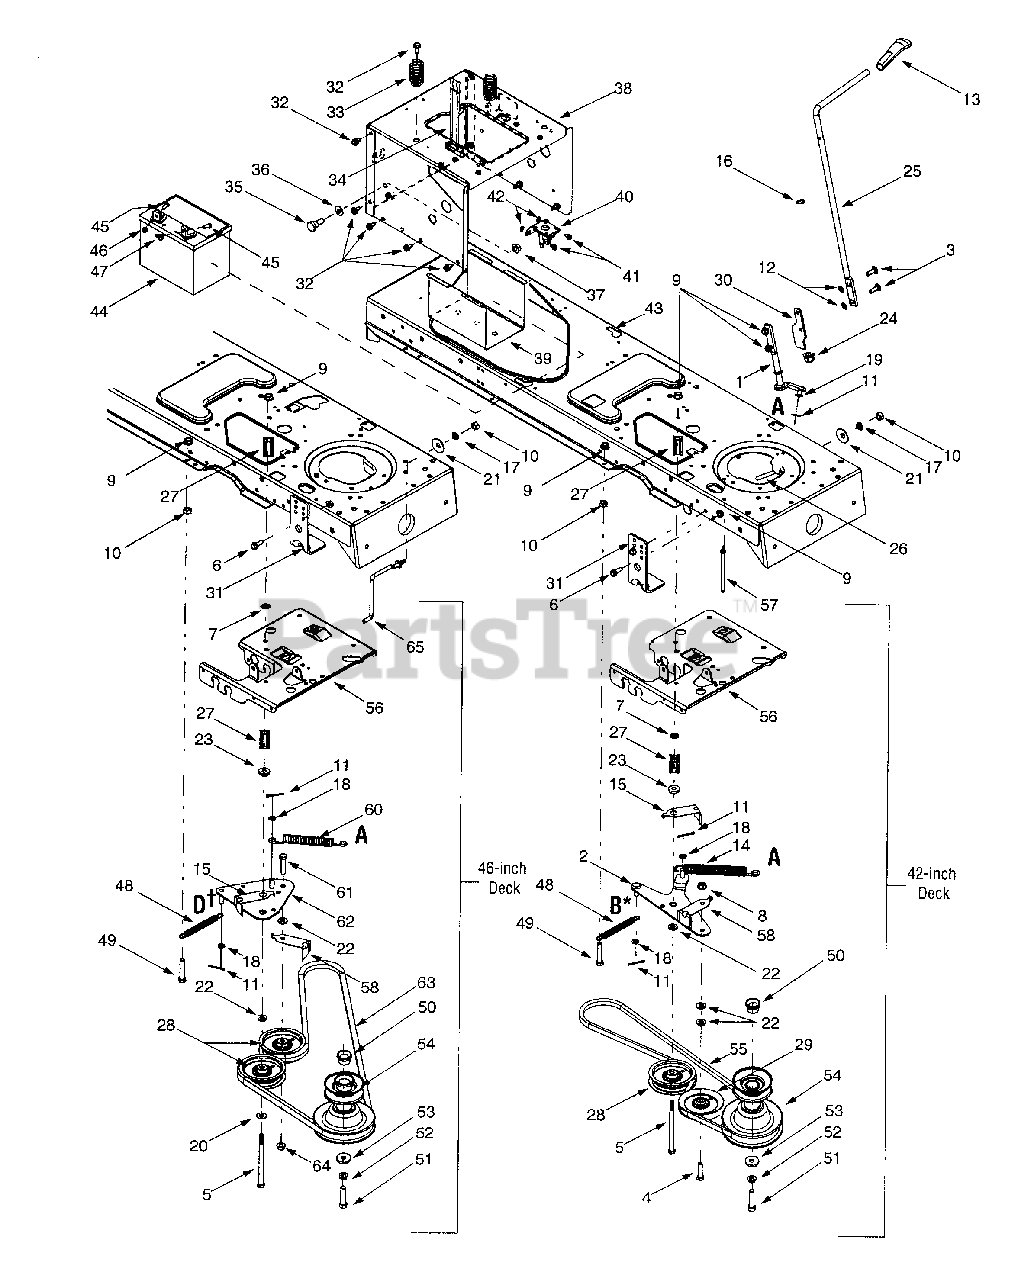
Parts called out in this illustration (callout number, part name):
1	PTO Engage Lever Assembly
4	Hex Cap Screw, 3/8-16 x 1.5
5	Hex Cap Screw, 3/8-16 x 5.5
6	Hex Head Washer Screw, 5/16-18 x .875
7	Push Nut, 3/8
8	Flange Lock Nut, 3/8-16
9	Flange Lock Nut, 5/16-18
10	Hex Nut, 5/16-18
11	Cotter Pin, 1/8 x 1.25
12	Speed Nut, .3125
13	PTO Knob
14	Extension Spring, .75 x 6.75
15	Belt Guard
16	Flat Washer, .510 x .750 x .033
17	Lock Washer, 5/16
18	Flat Washer, .385 x .62 x .063
19	Flat Washer, 5/16
20	Flat Washer, .406 x .875 x .059
21	Bell Washer, .39 x 1.13 x .062
22	Flat Washer, .407 x .812 x .135
23	Shoulder Spacer, .380
24	Hex Split Flange Bearing, .5
26	Belt Keeper Rod
27	Spacer, 3/8 x 1.54
28	Idler Pulley, 3.5
29	Idler Pulley, 4.0
32	Self Tapping Screw, 5/16-18 x .625
33	Compression Spring, 1.28 x 3.5
34	Battery Strap
35	Shoulder Screw, .625 x .5, 7/16-20
36	Bell Washer, .45 x 1.0 x .062
37	Flange Lock Nut, 7/16-20
41	Self Tapping Screw, 1/4-20 x.5
42	Lock Washer, 1/4
45	Hex Cap Screw, 1/4-20 x .62
46	Hex Sems Nut, 1/4-20
47	Wing Nut, 1/4-20
48	Extension Spring, .50 x 5.0
49	Hex Cap Screw, 5/16-18 x 1.75
50	Spacer Cup
51	Hex Head Cap Screw, 7/16-20 x 1.25
52	Lock Washer, 7/16
53	Flat Washer, .450 x 1.25
54	Engine Pulley, 3.56 OD x 5.56
55	PTO Belt
57	Keeper Pin, 5/16 x 4.75
58	Belt Guard
60	Extension Spring, .75 x 6.75
61	Hex Cap Screw, 3/8-16 x 1.75
63	PTO Belt
64	Flange Lock Nut, 3/8-16
65	Belt Keeper Rod
